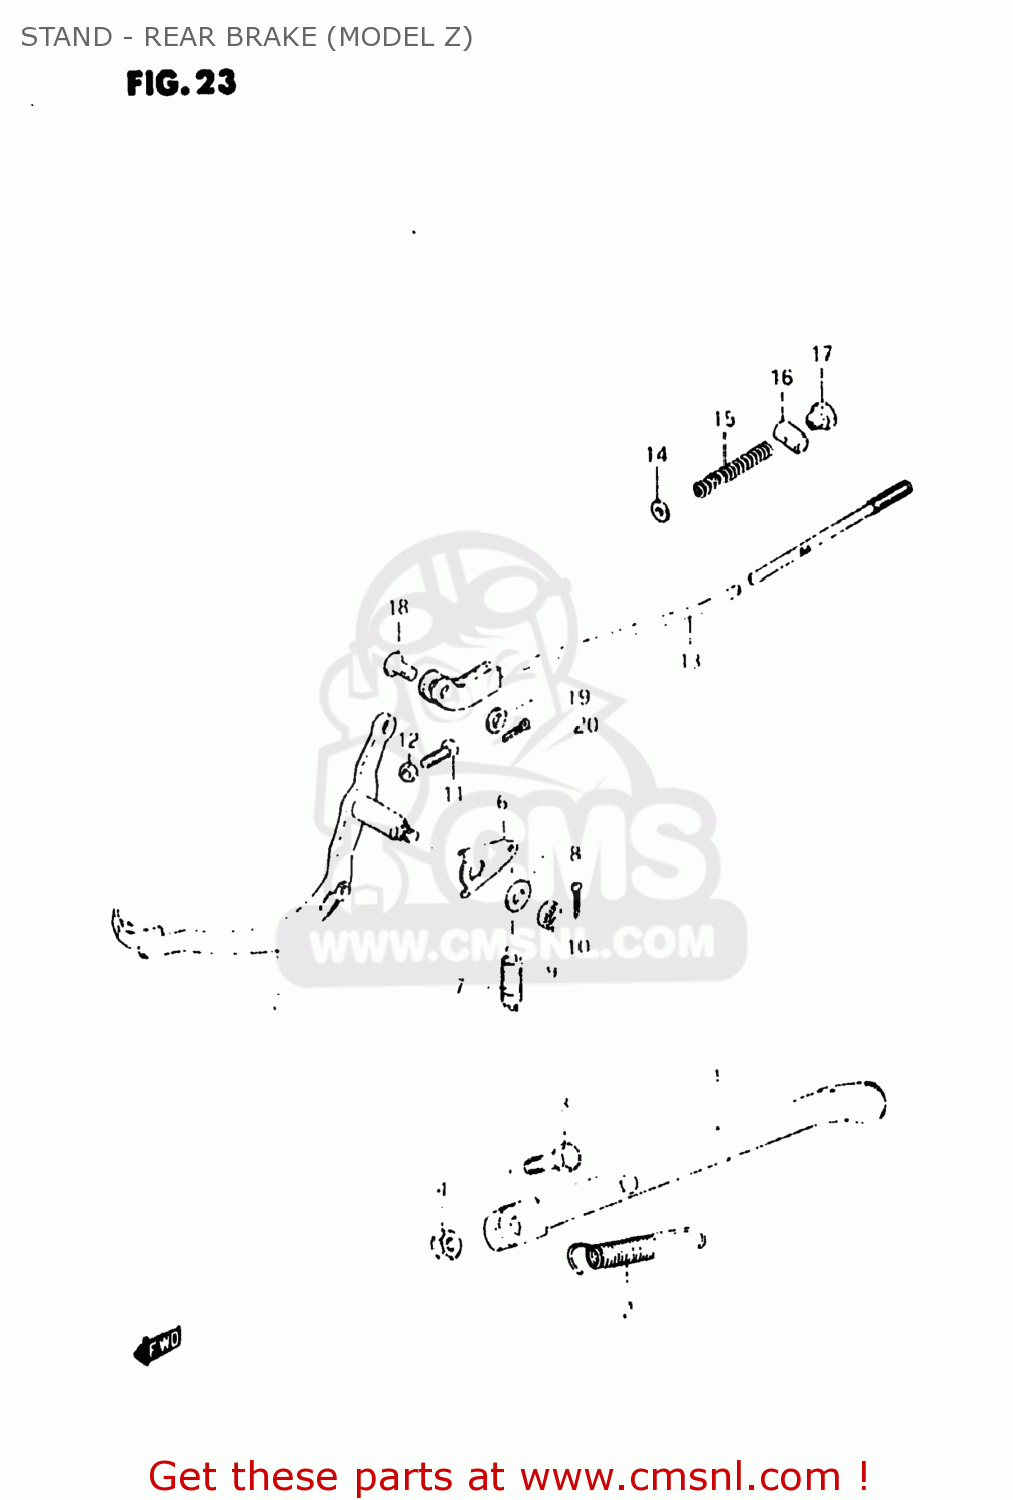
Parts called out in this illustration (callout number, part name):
1	STAND,SIDE
2	SPRING
3	BOLT(10X30)
4	NUT
5	PEDAL,BRAKE
6	ARM,BRAKE RETURN SPRING
7	SPRING
8	WASHER
9	NUT 8MM
10	PIN 20X20
11	BOLT(6X23)
12	NUT
13	ROD ASSEMBLY,REAR BRAKE
14	WASHER
15	SPRING
16	PIN(11X18)
17	NUT
18	PIN
19	WASHER
20	PIN 20X20
